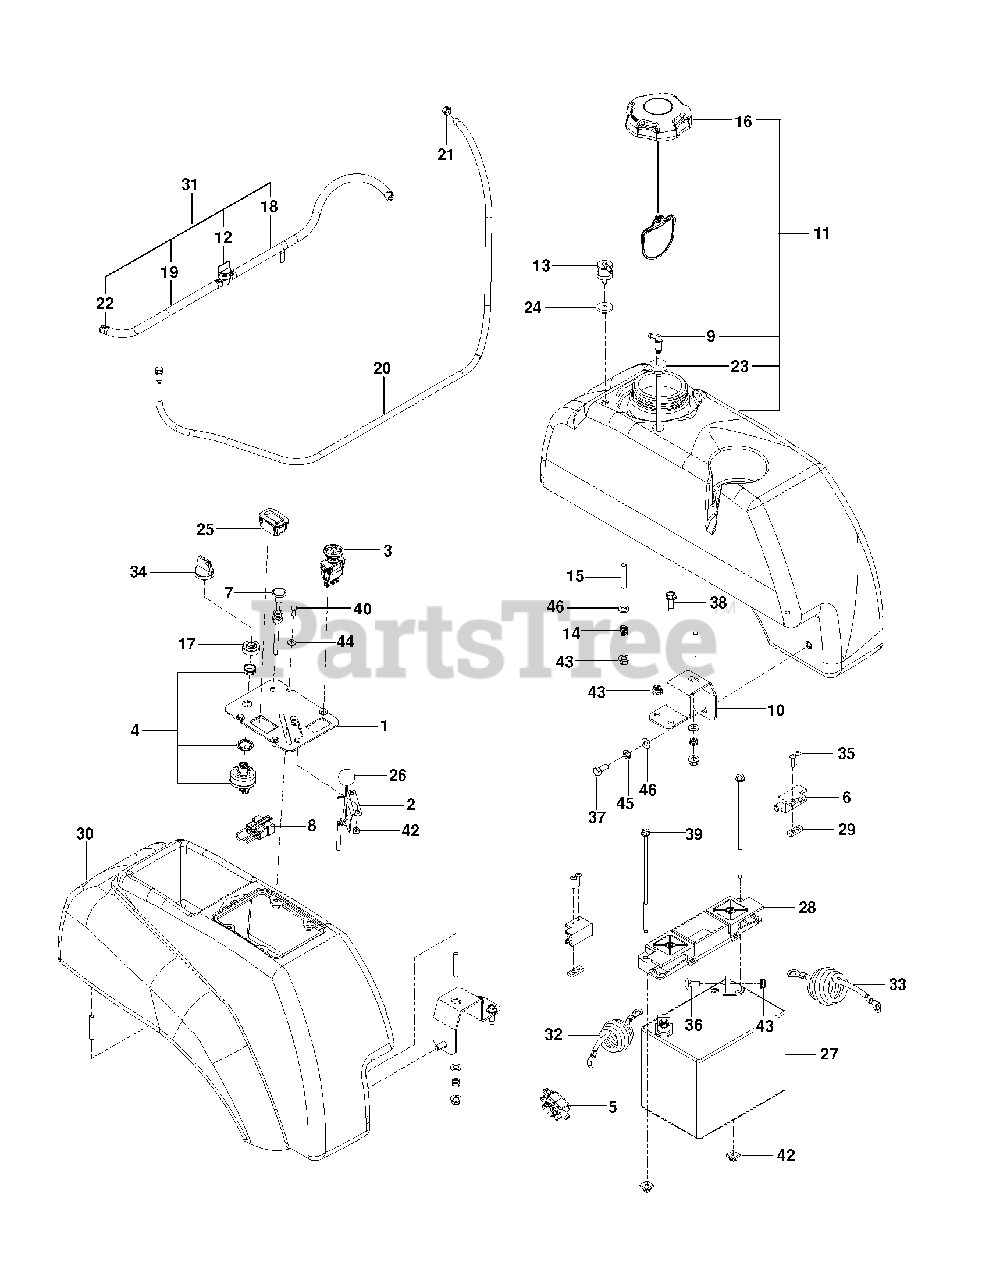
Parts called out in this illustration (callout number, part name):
1	PLATE.CONSOLE.BLACK
2	THROTTLE CABLE
3	SWITCH, PTO 10 AMP
4	SWITCH, IGNITION, INDAK
5	SWITCH, BRAKE 3P
6	SWITCH INTERLOCKT
7	CABLE, CHOKE, 38
8	PLUG, TIMER
9	FITTING, FUEL
10	SUPPORT, TANK, BLK
11	TANK FUEL LT ASM MZ GRAY
12	FUEL VALVE
13	VALVE.FUEL.CHECK
15	STUD, 5/16C
16	CAP, FUEL
17	CAP IGNITION NUT
18	HOSE, FUEL .25 ID X 26"
19	GAS LINE 10"
20	HOSE, VAPOR 3/16 X 48"
21	CLAMP, HOSE
22	HOSE CLAMP
23	RUBBER GROMMET
24	GROMMET, CHECK VALVE
25	RP GUAGE.SRVCMNDR.HRMTR.
26	KNOB.ROUND.BALL.BLACK
27	BATTERY, 12 V 330 AMP
28	BATTERY HOLD DOWN
29	TAPPED PLATE
30	FENDER CONSOLE
31	FUEL LINE ASM
32	POST.CABLE LONG
33	NEG. CABLE, 28"
34	KEY, IGNITION
35	SCR #10-24 X .75 SKT HD BLK
36	BOLT 5/16C X 3/4" CARRIAGE
37	HCS 5/16C X 3/4
38	RP BLT 5/16-18 X 1 THRD FORM D
39	Bolt, 1/4-20 X 7.5
40	HCS #10-24 X 1/2
41	SCR #10-24 X .75 SKT HD BLK
42	PUSH NUT-NYLON
43	5/16-18 NYLOC FLANGE NUT
44	WASHER #10
45	WASHER 5/16 LOCK
46	FLAT WASHER 5/16 SAE
